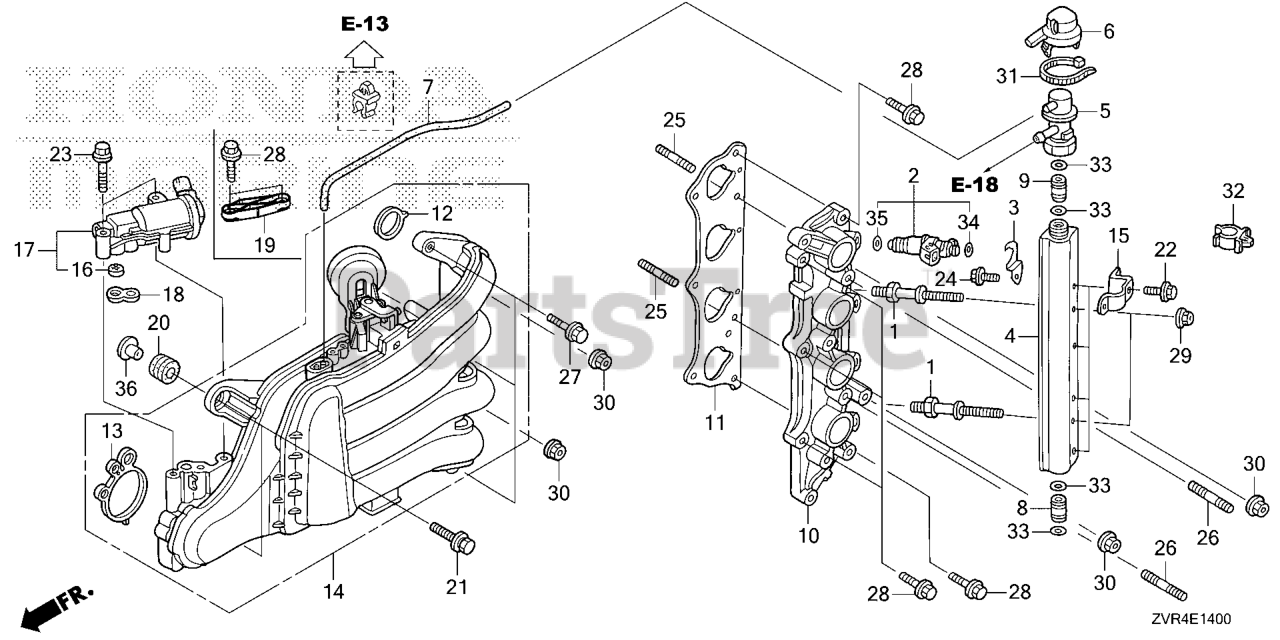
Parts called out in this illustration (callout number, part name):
1	BOLT, FUEL PIPE
2	INJECTOR ASSY., FUEL
3	CLIP, INJECTOR
4	LINE, FUEL
5	REGULATOR ASSY., PRESSURE
6	CAP, REGULATOR
7	TUBE, PRESSURE REGULATOR CONTROL
8	JOINT, FUEL PIPE
9	JOINT, FUEL PIPE
10	BASE, INJECTOR *NH8* (DARK GRAY)
11	GASKET A, INJECTOR BASE
12	GASKET, IN. MANIFOLD
13	GASKET, THROTTLE BODY
14	MANIFOLD, INLET
15	BRACKET A, HARNESS CLIP
18	GASKET, ELECTRONIC AIR CONTROL VALVE
19	COVER, AIR PATH
20	RUBBER, FR. CARRIER CUSHION
21	BOLT-WASHER (8X35)
22	BOLT, FLANGE (6X14)
24	BOLT (6X10)
25	BOLT 2, STUD (8X25)
26	BOLT, STUD (8X32)
27	BOLT, FLANGE (8X35)
28	BOLT, FLANGE (8X25)
29	NUT, FLANGE (6MM)
30	NUT, FLANGE (8MM)
31	BAND, HARNESS
32	CLIP, FUEL TUBE (14) (NOT AVAILABLE)
33	O-RING (7.8X1.9) (ARAI)
34	O-RING (7.47X3.6)
35	O-RING (7.45X3.61) (NOK)
36	COLLAR (8.5X14.5)
